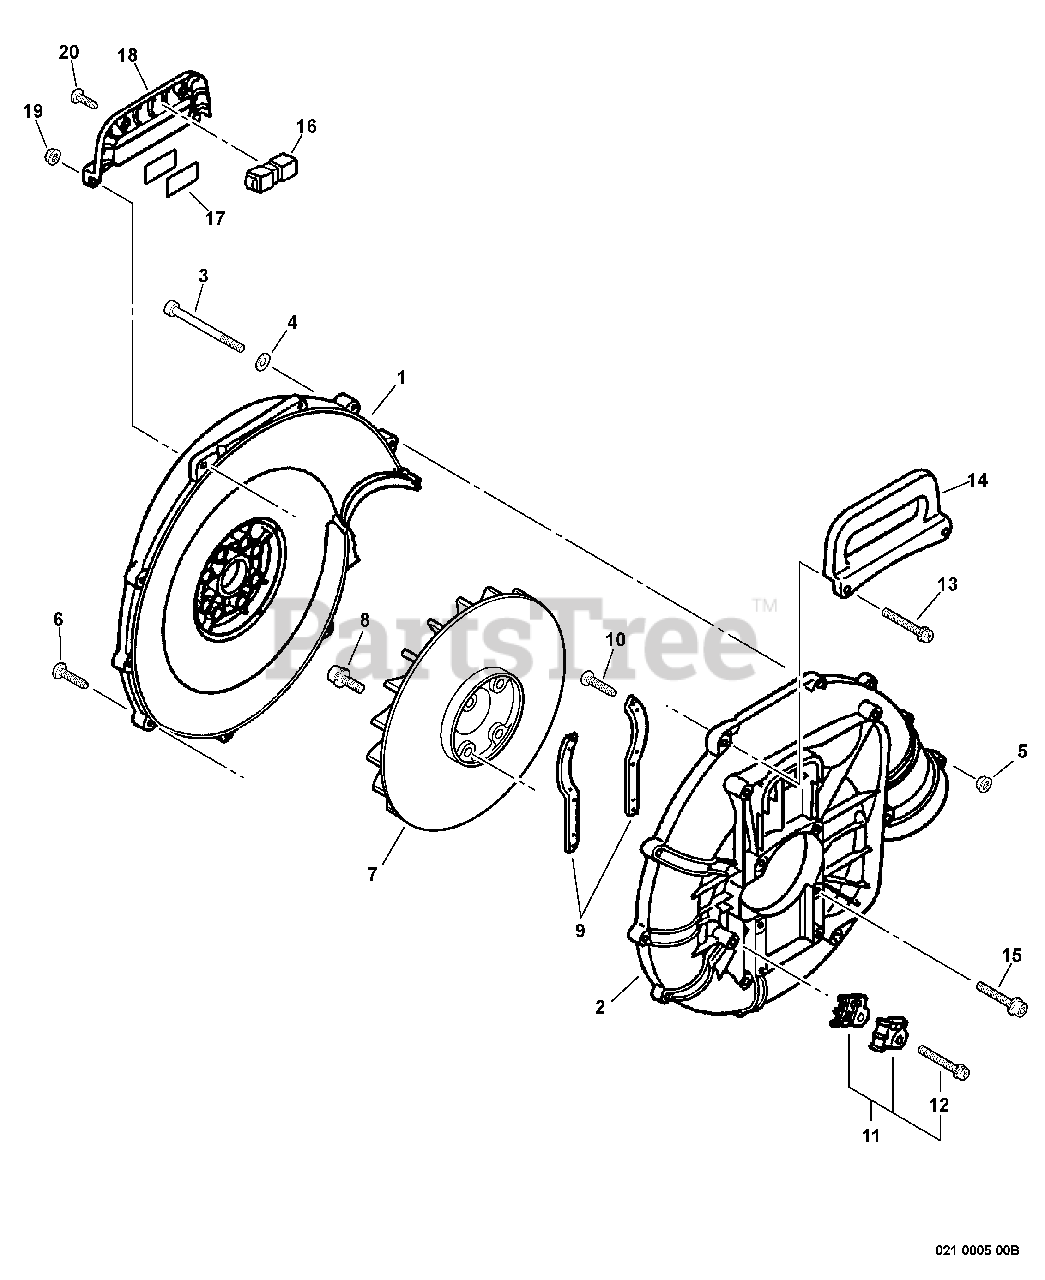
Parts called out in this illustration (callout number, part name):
1	COVER, FAN - INNER
2	COVER, FAN - OUTER
3	BOLT 5×60
4	WASHER 5.3×10×1
5	NUT, FLANGE M5
6	SCREW 5×30
7	FAN
8	BOLT 5×20
9	BRACKET, ENGINE
10	SCREW TAPPING 3×12
11	CABLE HOLDER KIT
12	SCREW 5×25
13	SCREW 5×45
15	SCREW 5×32
18	HANDLE
19	NUT, FLANGE M5
20	SCREW 5×16
